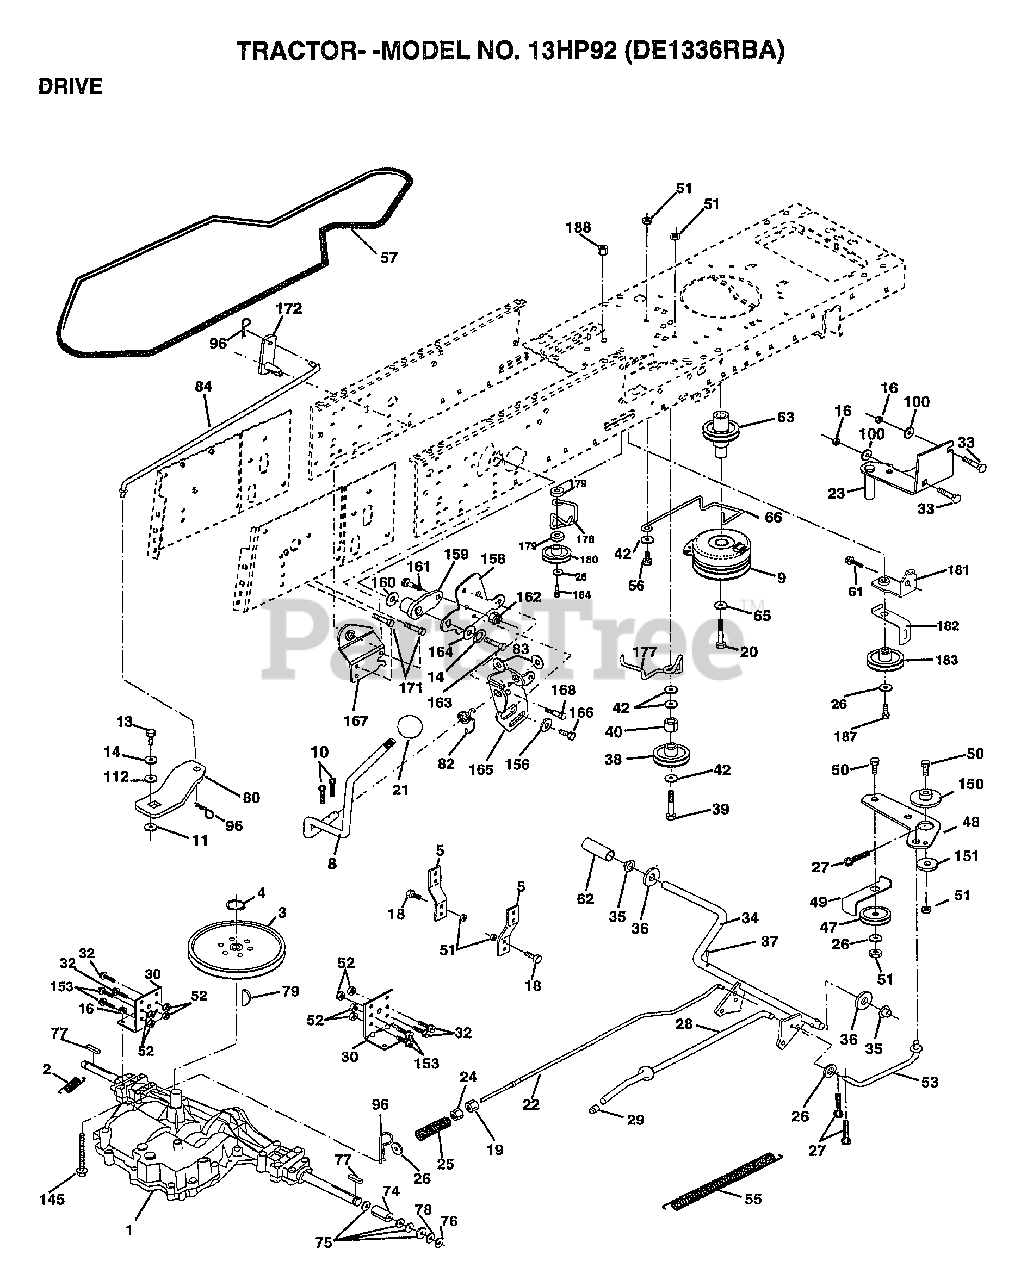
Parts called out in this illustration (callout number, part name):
2	SPRING.BRAKE.RETU
3	"PULLEY.TRANSAXLE.7"""
5	STRAP TORQUE
8	ROD.SHIFT.FENDER.ADJ.LT.CRD
9	CLUTCH.ELEC.EVX
10	PIN COTTER 1/8
11	WASH-SHFT PLT LT
13	BOLT.1/4-28.W/PAT
14	LOCKWASHER
16	NUT
18	BOLT
19	NUT
20	BOLT.7/16-20X4.25
21	KNOB T (1/2-HOLE)
22	ROD.BRAKE.PMST.CRD
23	BRACKET.CLUT.MTG.
24	NUT
25	SPRING ROD LT
26	WASHER
27	COTTER PIN
28	ROD.BRAKE.PARK.LT
29	PLUNGER CAP T
30	TRANSAXLE MTG BKT
32	BOLT
33	BOLT
34	SHAFT.ASM.PEDAL.FOOT.CRD
35	NYLON BEARING
36	WASHER LT
38	PULLEY.FLAT
39	BOLT
40	SPACER T
42	WASHER
48	BELLCRANK.CLUTCH
49	RETAIN BELT
53	"LINK, CLUTCH T"
55	"SPRING, RETURN LT"
57	"V-BELT.KEV.111"""
61	SCREW
62	PEDAL COVER T
63	PULLEY.CLUTCH.EVX
65	LOCKWASHER
66	KEEPER-BELT
74	SPACER AXLE
75	WASHER
76	E-RING LT
77	SQUARE KEY
78	WASHER
80	"ARM.SHIFT.20""TIRE"
82	"SPRING,TORSION"
83	WASHER
84	LINK.SHIFT.CRD
96	RETAINER M
100	WASHER M
112	WASHER LT
145	BOLT.HEX.FLGHD
150	BUSHING.BELLCRANK.GRD.DR
151	WASHER
156	WASHER.SRRTD.5/16
158	BRKT.SHIFT.MOUNT
159	HUB.SHIFT
160	WASHER
161	BOLT T
164	WASHER.5/8X.281X10GA
165	BRKT.PIVOT.LEVER
166	SCREW.5/16-18X5/8
167	BRKT.SUPT.SHIFT.CRD
168	BOLT.SHOULDER.5/16-18X.561
169	PLATE.FASTENING
171	SCREW LT
172	SHAFT.ASM.SHIFT.FRT.CRD
177	KEEPOER.FLAT.IDLER
178	KEEPER.BELT.IDLER
179	WASHER
180	PULLEY.FLAT.IDLER
181	BRKT.IDLER.GRD.DR.CRD
182	"KEEPER.BELT.2.5"".OD.CRD"
183	PULLEY.V-IDLER
184	SCREW.HXWSH.3/8
187	SCREW
